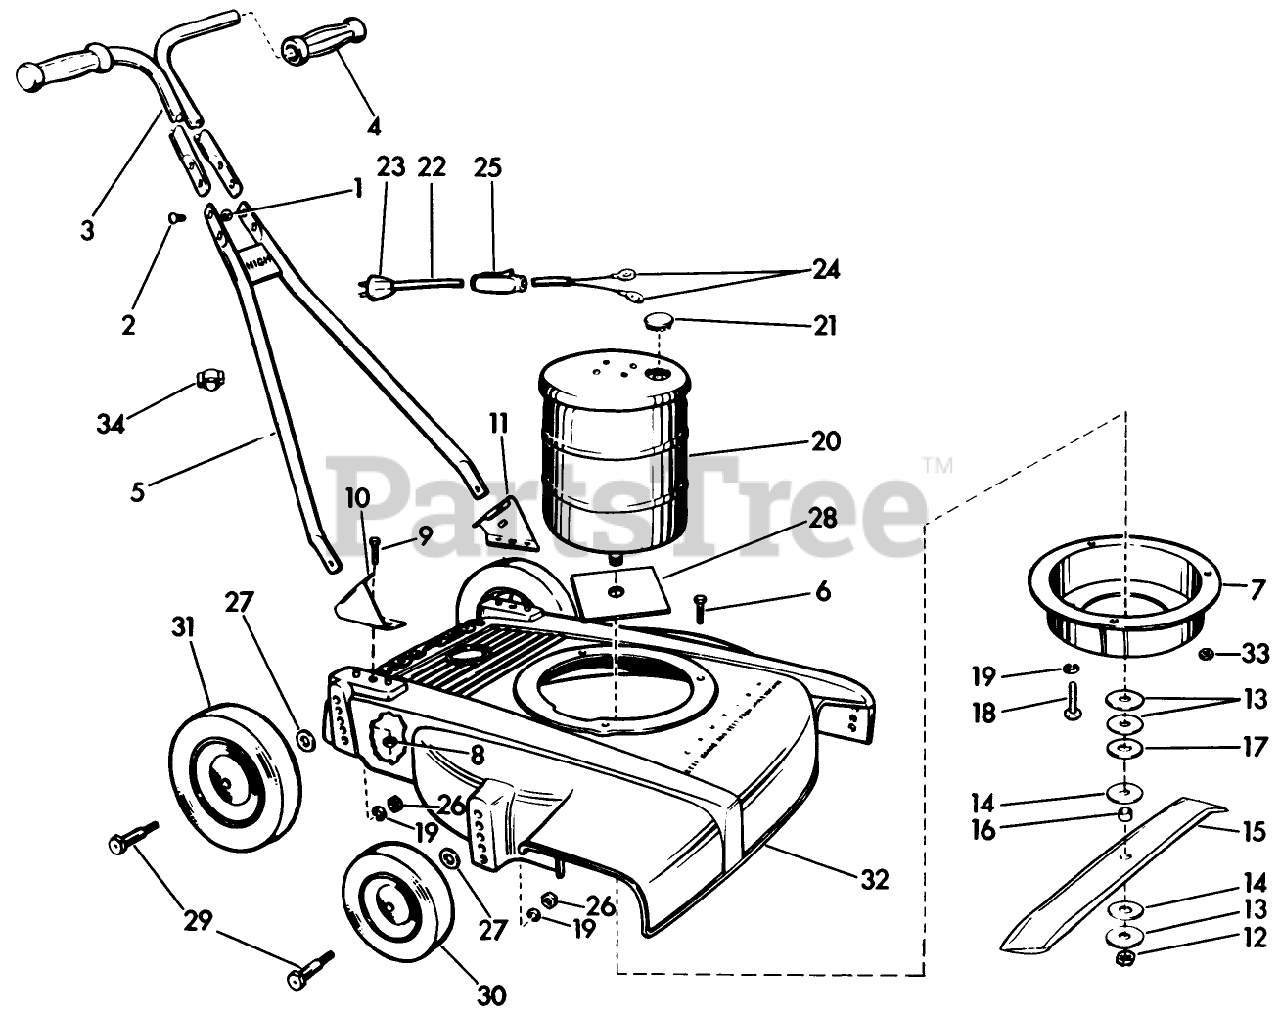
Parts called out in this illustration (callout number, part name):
1	STOP NUT
7	Plate-Adapter
7	Adapter Plate
15	Blade-18"
16	Bushing-Blade
17	BLADE WASHER
18	Screw-Motor Mounting
19	WASHER, LOCK
21	Cap-Snap-on
23	Plug-Electric
24	Lug-Electric
25	Switch-Toggle
28	Shield-Dust
32	Housing-18"
34	Clip-Electric Cord
